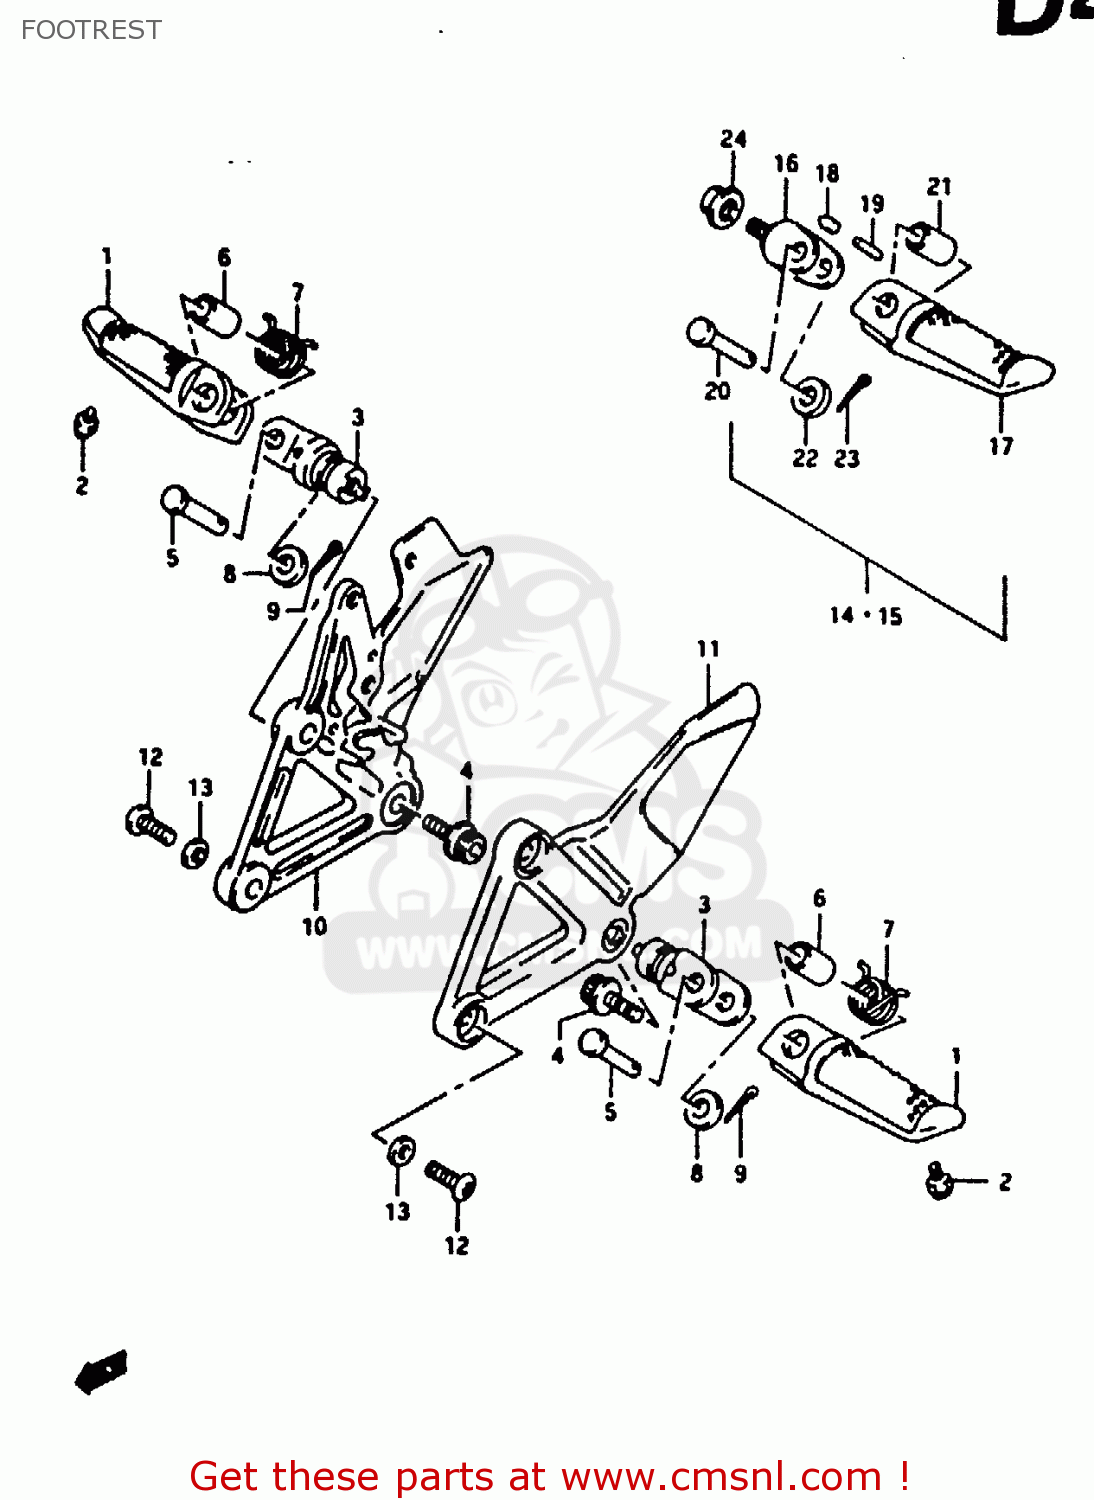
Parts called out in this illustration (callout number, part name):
1	BAR,FR FOOTREST,R
2	BOLT(6X6)
3	HOLDER,FOOTREST
4	BOLT(10X24)
5	PIN
6	SPACER(8.1X12X22)
7	SPRING
8	WASHER
9	PIN 20X15
10	BRACKET,FR FOOTREST,R
11	BRACKET,FR FOOTREST,L
12	BOLT(8X20)
13	WASHER
14	FOOTREST ASSY, PILLION RH
15	FOOTREST ASSY, PILLION LH
16	HOLDER,PILLION FOOTREST
17	BAR,PILLION FOOTREST R
18	CUSHION,FOOTREST HOLDER
19	ROLLER,FOOTREST HOLDER
20	PIN
21	SPACER(8.1X12X22)
22	WASHER
23	PIN 20X15
24	NUT
